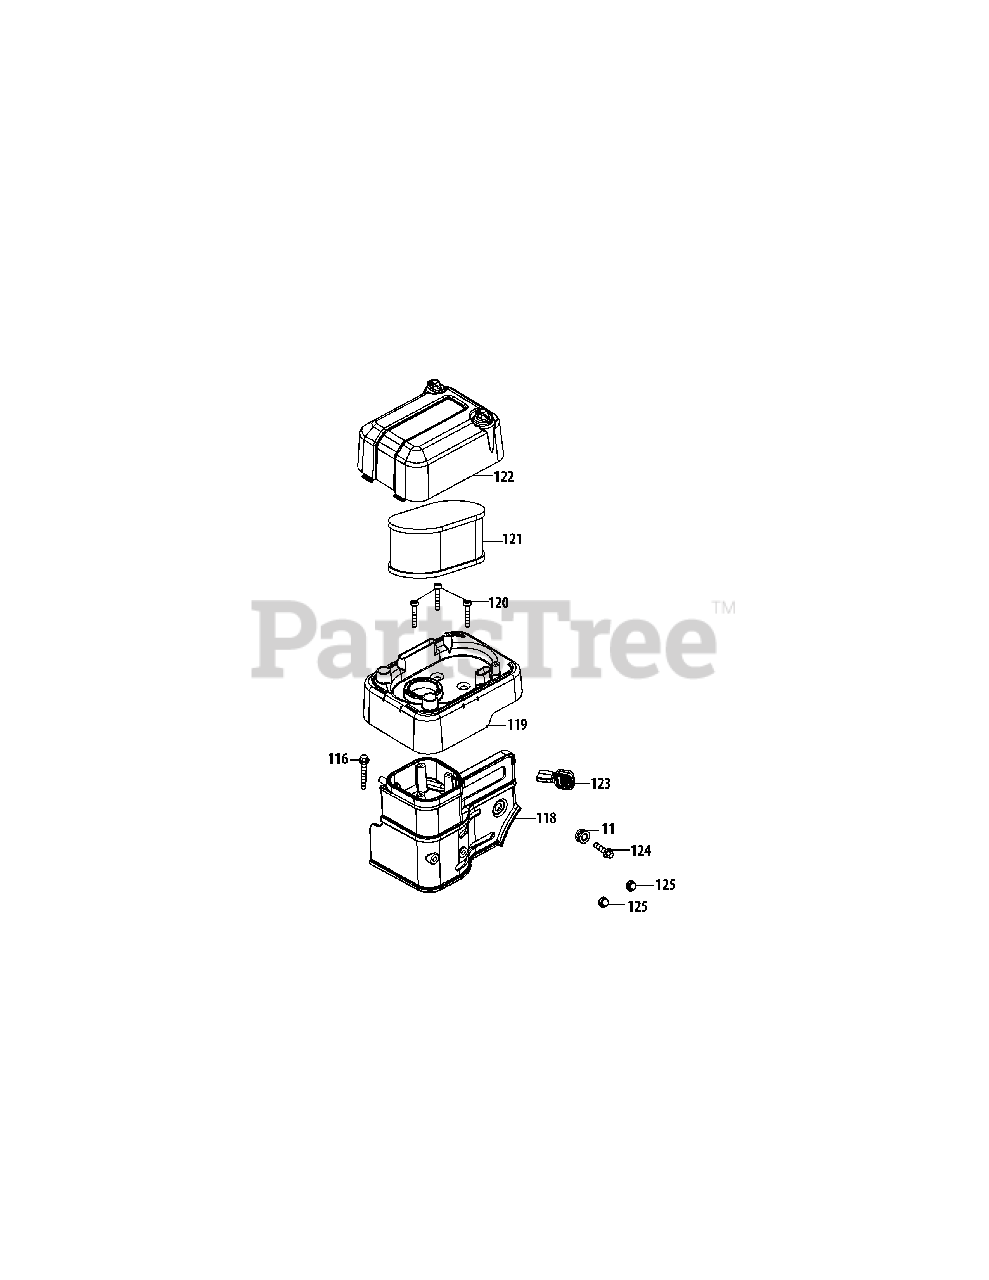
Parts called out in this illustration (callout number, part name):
11	Washer, Flat
116	Bolt M6×30
118	Air Filter Housing
119	Air Filter Base
120	Countersunk Screw
121	Air Filter Assembly
122	Air Filter Cover
123	Throttle Control Knob
124	Bolt M6×16
125	Plate-Shaped Nut
